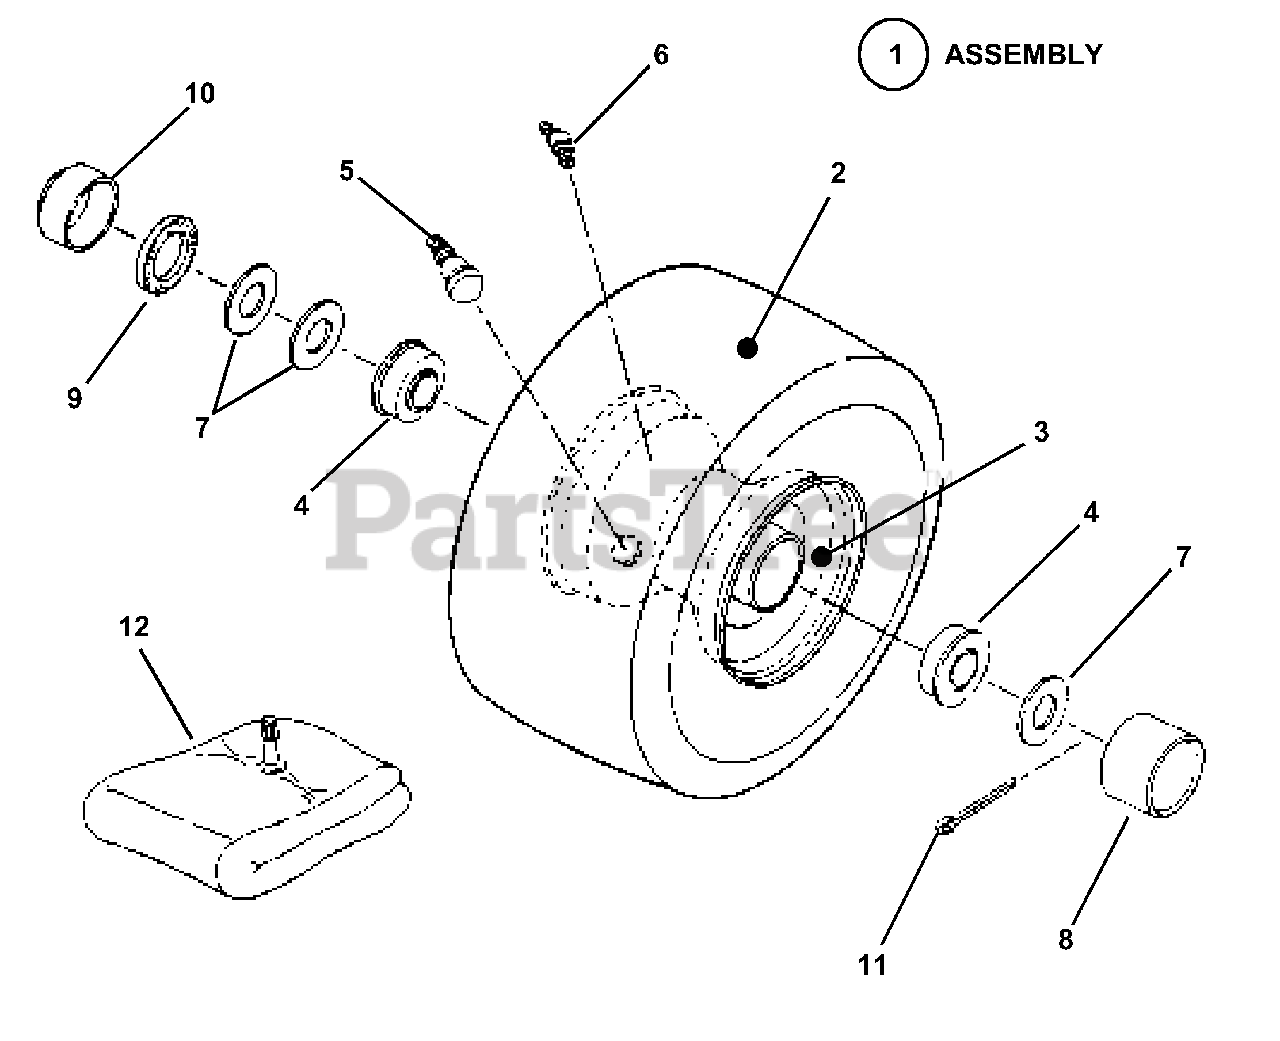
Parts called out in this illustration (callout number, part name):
1	ASSEMBLY, Tire & Rim
2	TIRE, 4.10/3.50 x 4
3	RIM
4	BEARING, Ball
5	VALVE, Air (Snap-in)
6	FITTING Lube
7	WASHER
8	CAP, Hub
9	SEAL, Felt
10	CAP, Dust
11	PIN, 5/32 x 1" Cotter
12	TUBE, Inner
